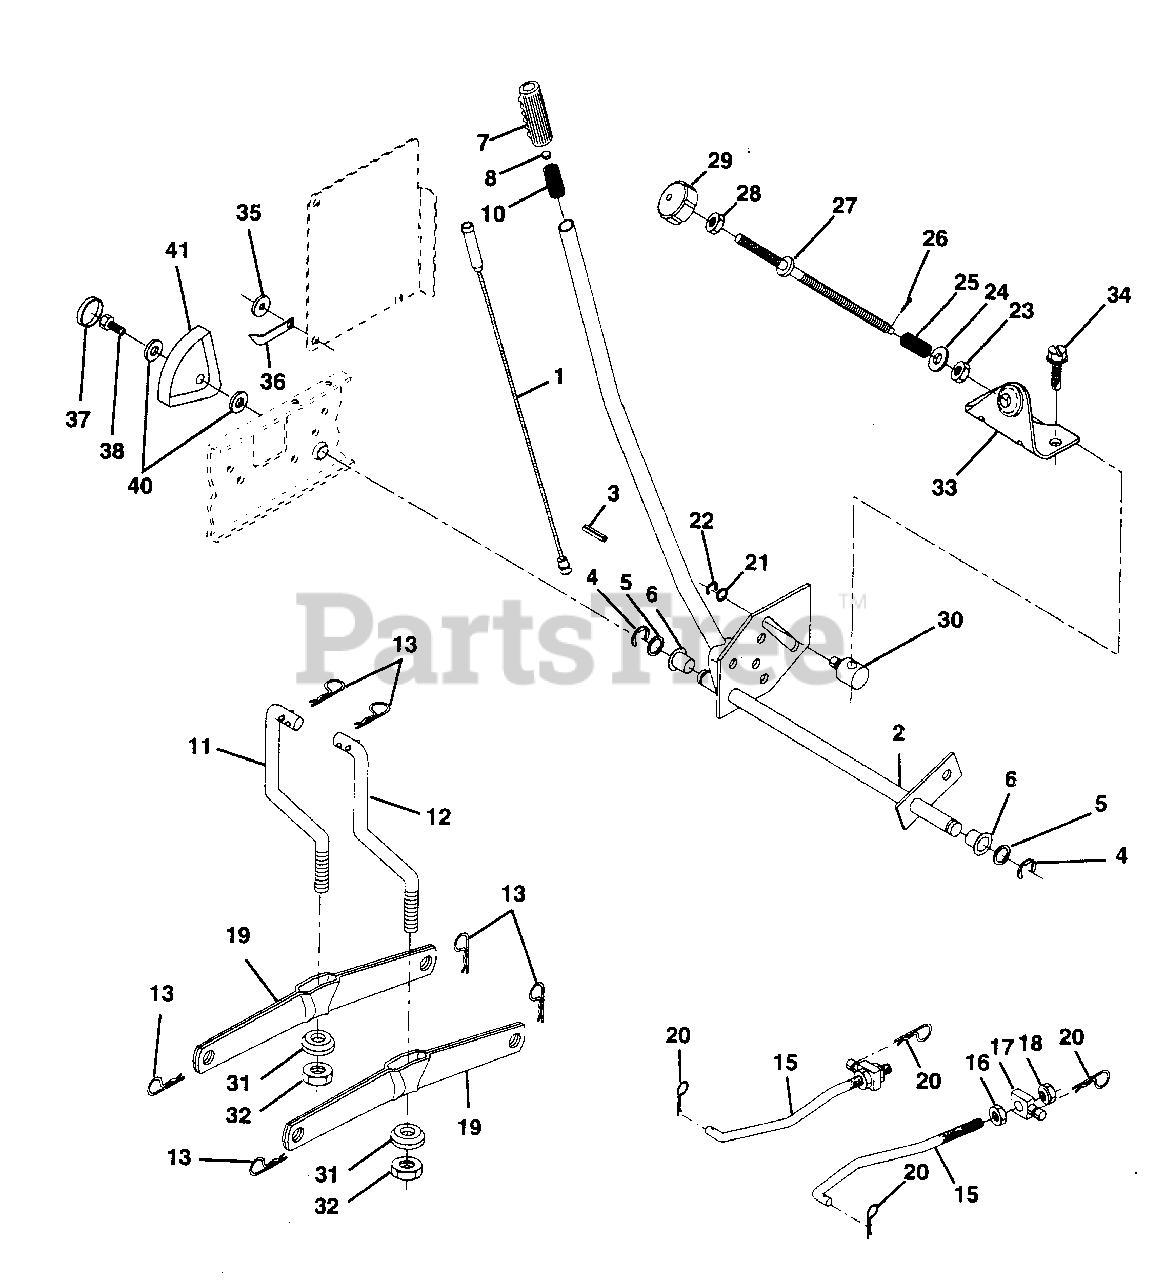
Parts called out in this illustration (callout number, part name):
1	Wire Asm Inner W/plunger 17 32 (AYP part number)
2	Shaft Asm Lift (AYP part number)
3	Pin Groove (AYP part number)
4	E Ring #5133-62 (AYP part number)
5	Washer PLTD 21/32 X 1 X 21 ga (AYP part number)
6	Bearing Nylon Blk 629 Id (AYP part number)
7	Grip Handle Bicycle Matte Blk (AYP part number)
8	Button Plunger Black (AYP part number)
10	Spring Cprsn 3 750 Oiled
11	Link Lift LH (AYP part number)
12	Link Lift RH
13	Retainer Spring (AYP part number)
15	Link Front (AYP part number)
16	Nut Jam Hex 1/2-13 Unc (AYP part number)
17	Trunnion Blk Zinc (AYP part number)
18	Nut Lock W/wsh 1/2-13unc (AYP part number)
19	Arm Suspension Rear (AYP part number)
20	Spring, Retainer (AYP part number)
21	Washer 15/32 x 3/4 x 16 Ga. (AYP part number)
22	Ring Klip #T534037 (AYP part number)
23	Nut Special (AYP part number)
24	Washer 13/32 x 5/8 x 16 Ga. (AYP part number)
25	Spring 2-1/8" (AYP part number)
26	Pin cotter 3/32 x 1/2 (AYP part number)
27	Rod adj Lifte zino 7.49 work lg.
28	Nut Hex Jam 3/8 - 16 Unc. (AYP part number)
29	Knob info 3/8 - 16 Unc. Blk w/sym (AYP part number)
30	Turnnion dp. stop dbl thds plt.
31	Bearing Pvt. Lift Spherical (AYP part number)
32	Nut Crownlock 3/8-24 (AYP part number)
33	Bracket Stop inf. Hgt. (AYP part number)
34	Screw thdrol 3/8 - 16 x 1/2 Ty. TT (AYP part number)
35	Washer Nylon .44 x .75 x .032 (AYP part number)
36	Pointer Pnt Height Ind 505 (AYP part number)
37	Plug Hole Blk 1.485/1.515 Dia. (AYP part number)
38	Screw Thdrol 5/16-18 x 3/4
40	Washer 11/32 x 1-1/2 x 10 Ga. (AYP part number)
41	Scale Ind Height Blk (AYP part number)
